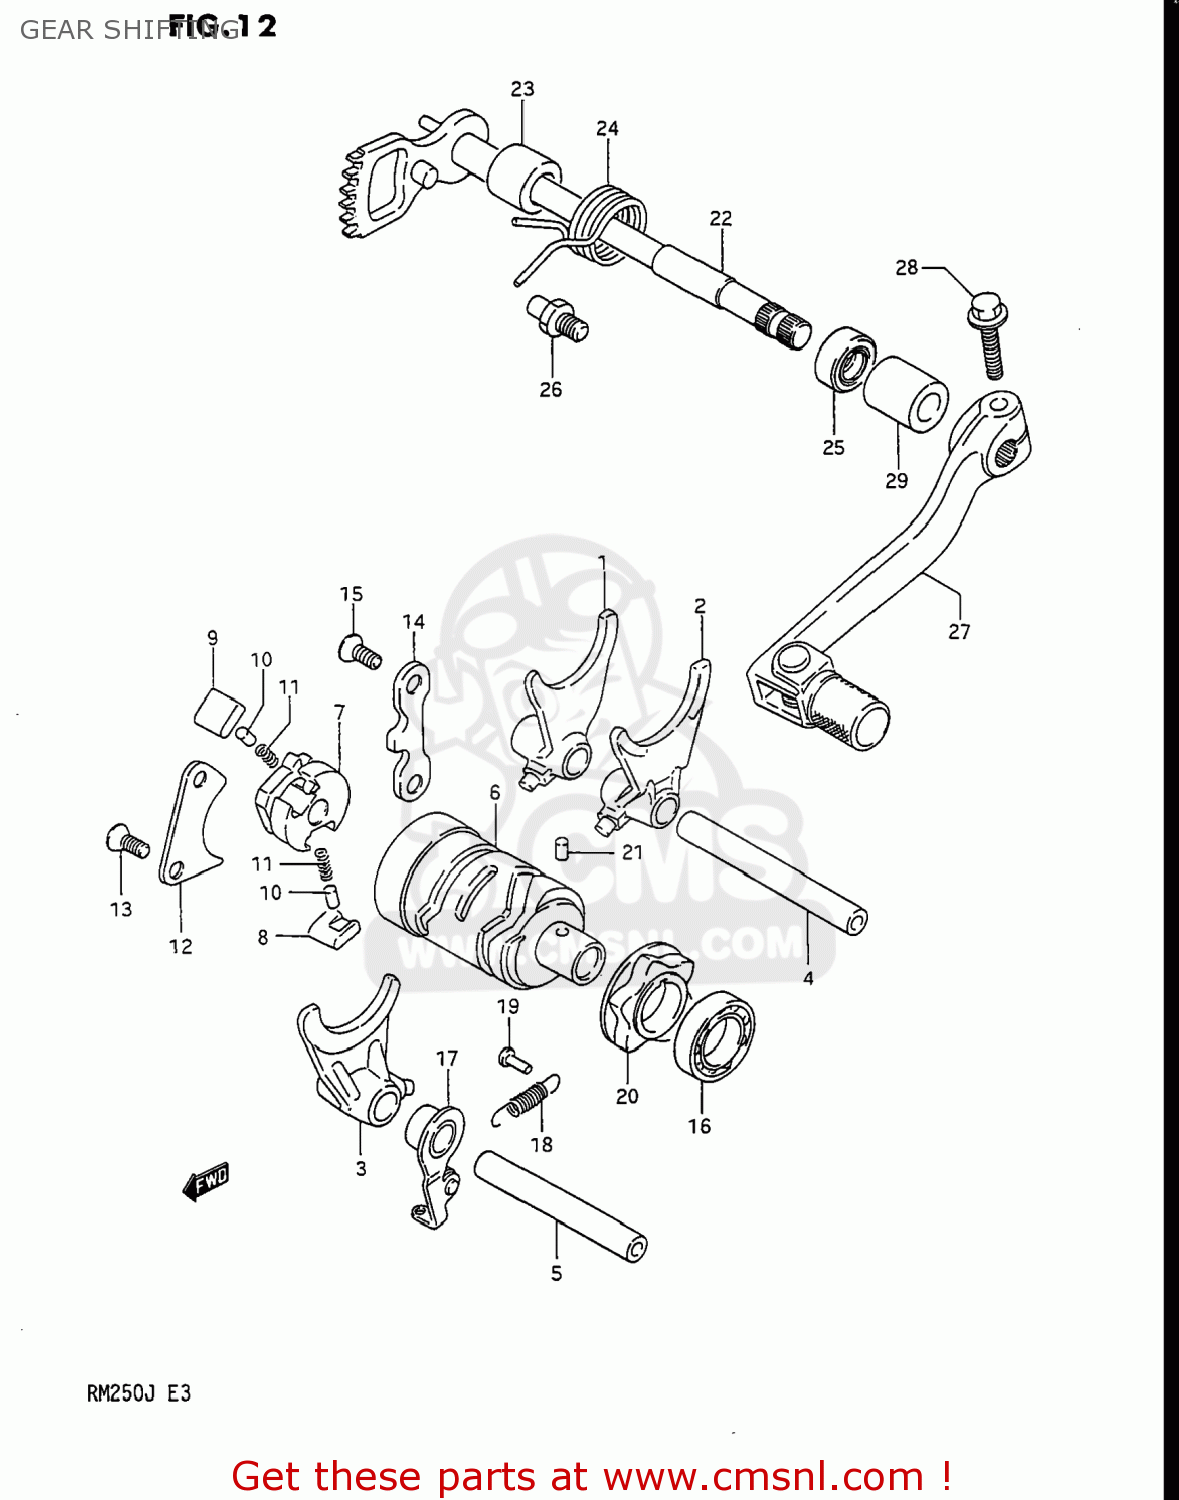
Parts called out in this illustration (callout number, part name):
1	FORK,GEAR SHIFT NO.1
2	FORK,GEAR SHIFT NO.2
3	FORK,GEAR SHIFT NO.3
4	SHAFT,GEAR SHIFT FORK
5	SHAFT,GEAR SHIFT FORK NO.2
6	CAM,GEAR SHIFT
7	GEAR,GEARSHIFT CAM DRIVE
8	PAWL,GEAR SHIFT NO.1
9	PAWL,GEAR SHIFT NO.2
10	PIN(5X8)
11	SPRING
12	LIFTER,GEAR SHIFT PAWL
13	SCREW
14	GUIDE,GEAR SHIFT CAM
15	SCREW
16	BEARING
17	STOPPER,GEAR SHIFTING CAM
18	SPRING
19	RIVET
20	PLATE,GEAR SHIFT CAM STOPPER
21	PIN
22	SHAFT COMP,GEAR SHIFTING
23	SPACER(12X20X15.3)
24	SPRING
25	OIL SEAL
26	STOPPER,GEAR SHIFT CAM
27	LEVER ASSY,GEAR SHIFT
28	BOLT
29	CUSHION 12X20X20
